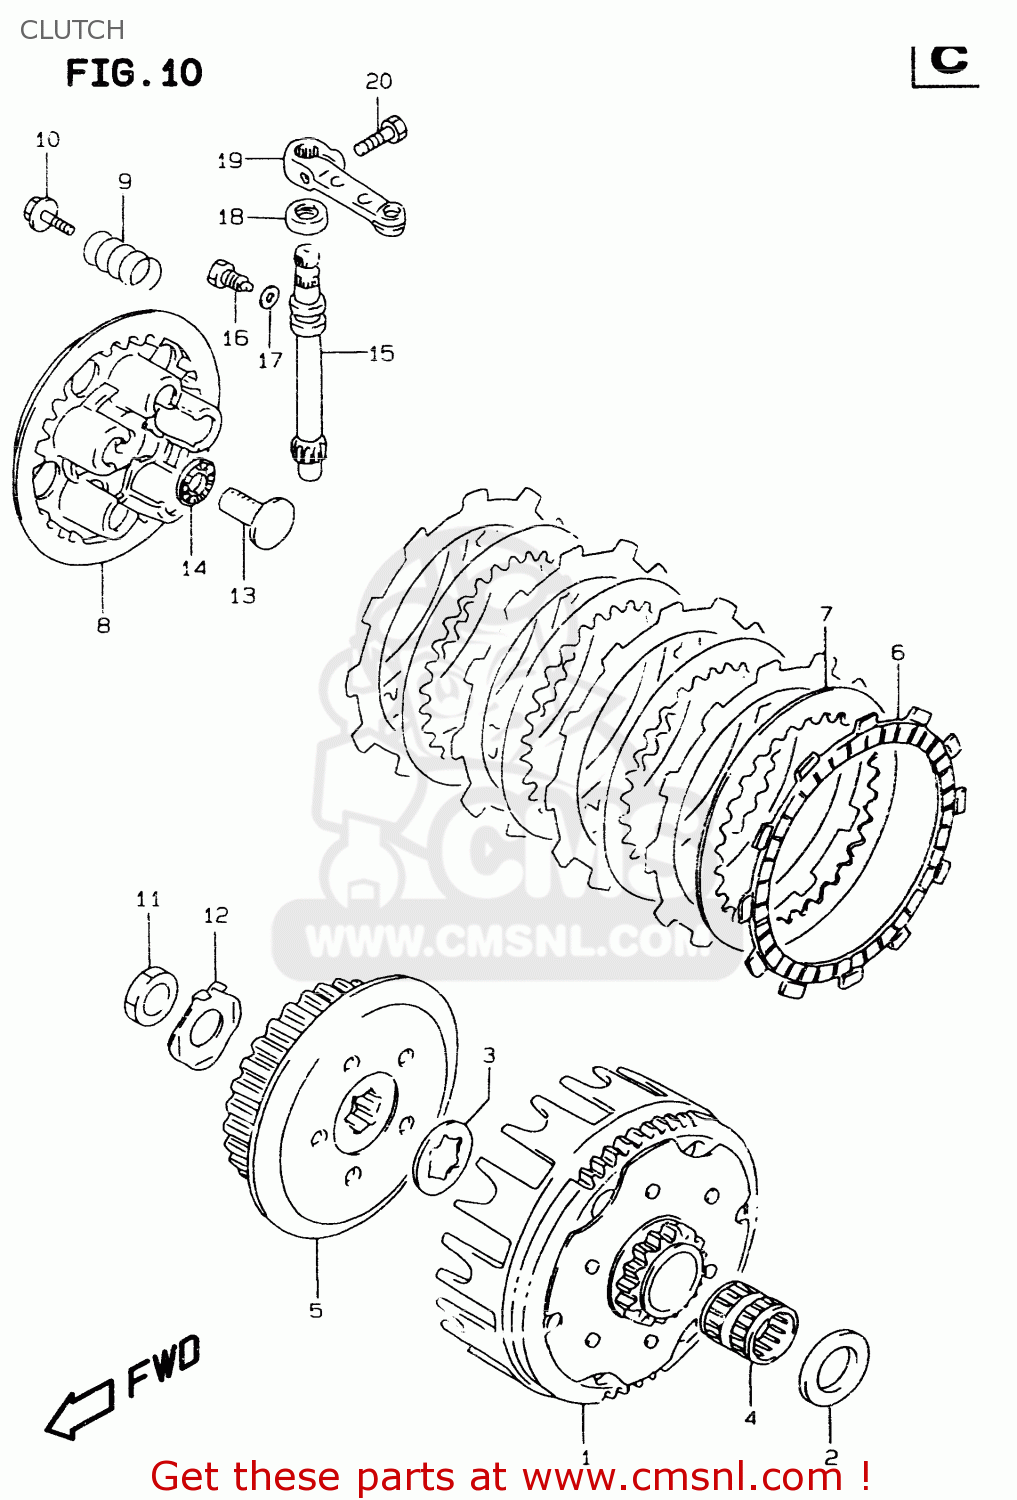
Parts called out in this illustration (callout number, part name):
1	GEAR ASSY,PRI DRIVEN(NT:62/16)
2	WASHER,THRUST
3	WASHER,LOCK
4	BEARING(20X25X26)
5	HUB COMP,CLUTCH SLEEVE
6	PLATE,CLUTCH DRIVE(T:3.0) (NAS)
7	PLATE,CLUTCH DRIVEN(T:2.0) (NAS)
8	DISC,CLUTCH PRESSURE
9	SPRING
10	BOLT 5X16
11	NUT
12	WASHER
13	RACK
14	BEARING(10X22X2.8)
15	PINION,CLUTCH RELEASE
16	BOLT
17	GASKET(6.2X11X1).2 (NAS)
18	SEAL,OIL(10X17X5)
19	ARM,CLUTCH RELEASE
20	BOLT
